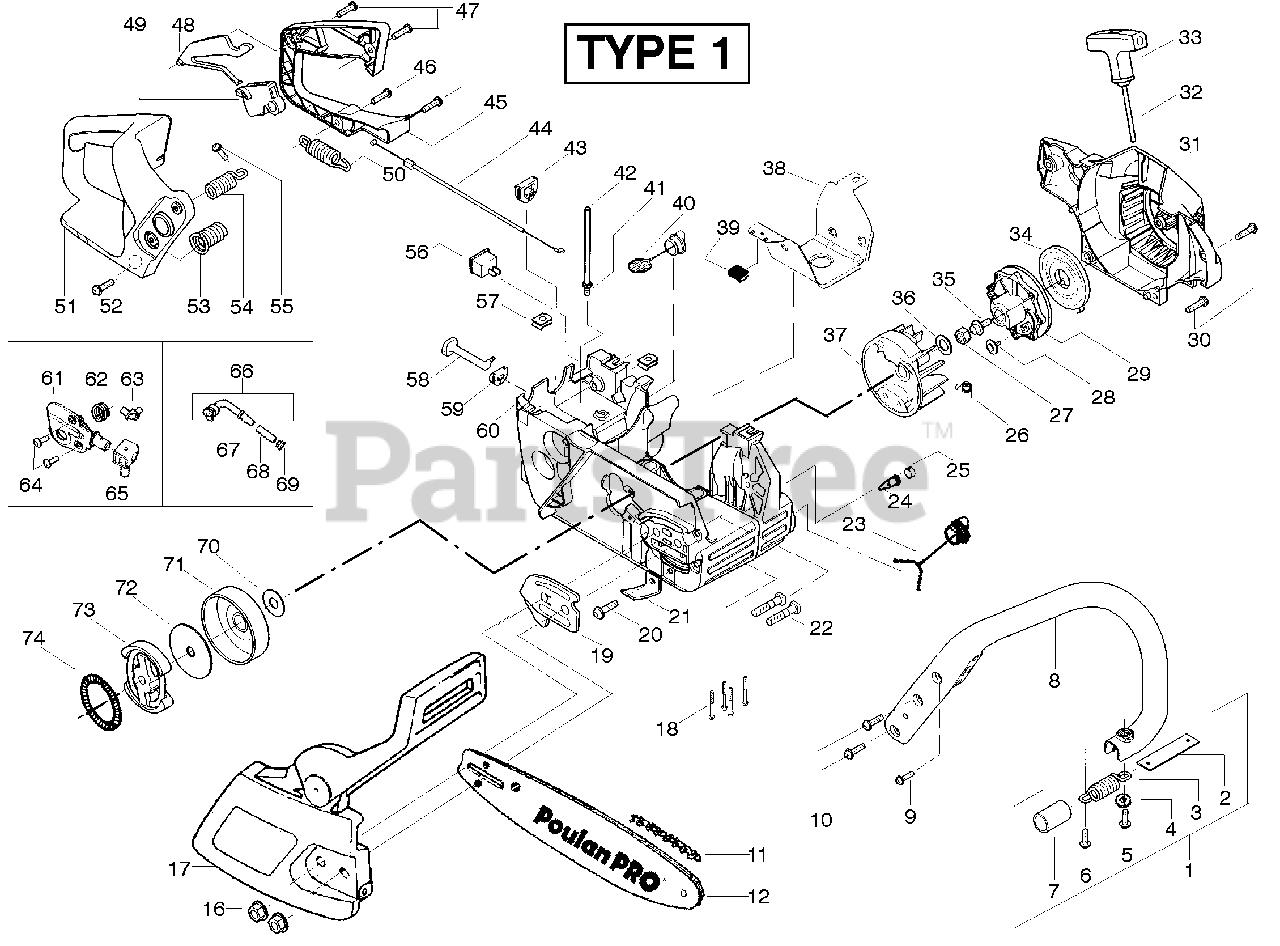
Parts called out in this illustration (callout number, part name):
1	Assy.- Isolator
2	Limiter Strap
3	Spring- Isolator
7	Sleeve-AV Spring
8	Front Handle
11	Chain-18"
16	Nut-Bar Mounting
17	Kit-Chain Brake
19	Plate-Bar Mounting
21	Chain Catcher
22	Bolt-Bar
23	Oil Cap Ass'y.
24	Check Valve
25	Plug-Bronze Vent
26	Spring-Starter Dog
27	Nut- Flywheel
29	Starter Pulley
31	Fan Housing
32	Kit - Rope
33	Starter Handle
34	Recoil Spring
36	Washer- Flywheel
37	Flywheel Ass'y.
38	Shield - Heat
39	Clip - "U"
40	Fuel Cap Ass'y.
41	Fitting- fuel line
42	Kit-Fuel line (large)
43	Grommet-Cable
44	Cable-Throttle
45	Cover-Rear Handle
48	Throttle Lockout
49	Trigger-Throttle
50	Spring- Isolator
51	Handle - Rear
53	Assy. Isolator - lower
54	Isolator Kit (Upper)
56	Kit-Switch
57	Nut- "U"-Type
58	Knob-Choke
59	Grommet-Knob
60	Chassis Ass'y.
61	Kit - Oil Pump
62	Gear-Worm Spring
63	Elbow-Oil Pickup
65	Seal Block
66	Oil Pick-up Ass'y
67	Pick-up Oiler
68	Oil Filter
69	Plug-Oil Filter
70	Washer-Thrust
71	Assy.-Clutch Drum w/bearing
72	Washer-Clutch
73	Assy. Clutch
74	Spring-Clutch
